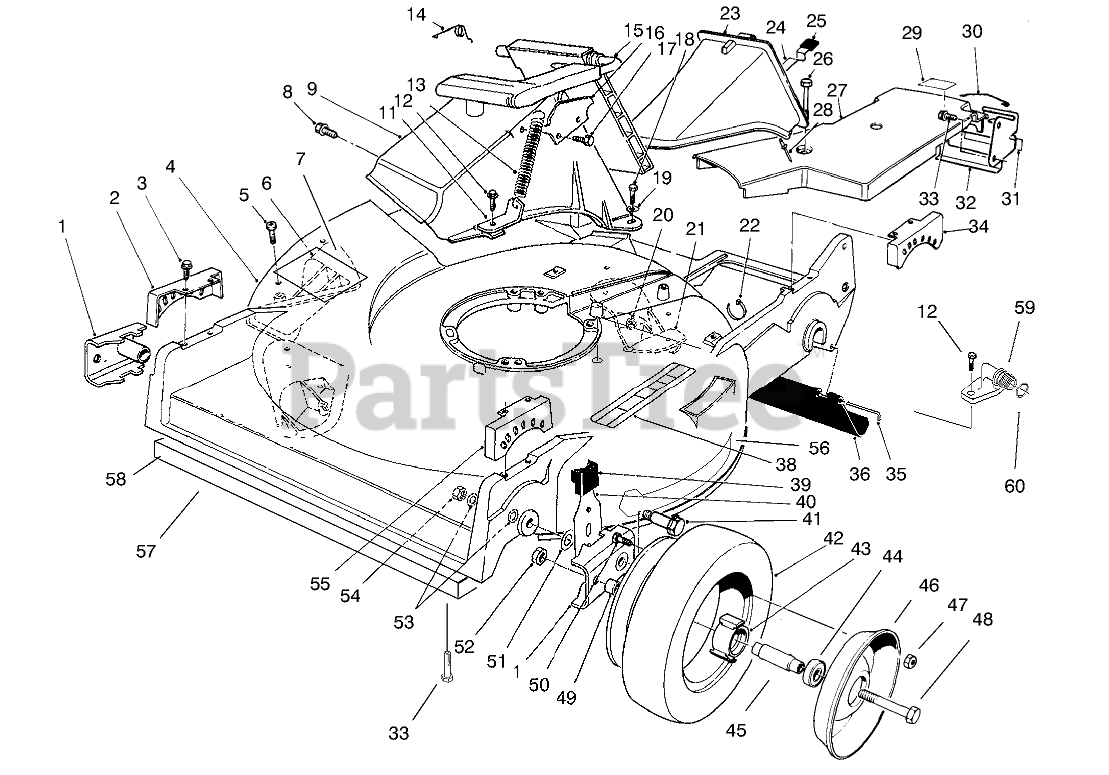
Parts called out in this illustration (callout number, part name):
1	ARM-PIVOT, FRONT
2	QUADRANT-FRONT, RH
3	SCREW-HWHTF
4	Housing-Commercial (Incl. Ref. #7)
5	SCREW-PPH
6	KICKER
7	DECAL-DANGER
8	SCREW AND WASHER ASM
9	DISCHARGE TUNNEL
11	Bracket-Spring
12	SCREW-HWH
13	SPRING-DOOR
14	RETAINER-DOOR
15	DOOR ASSEMBLY
16	DOOR LATCH PLATE
17	SCREW-PLASTITE
18	SCREW-HH
19	WASHER-FLAT
20	NUT-LOCK, NI
21	Plug-Discharge (Incl. Ref. #22, 23, & 28)
22	LATCH-PLUG, DISCHARGE
23	GRIP-LATCH
24	KICKER
25	PIN-COTTER
26	TIE-CABLE
27	SCREW-HHFTF
28	RIVET-HEAD, FLAT
29	BELT COVER
30	LABEL-GREASE
31	BRACKET-ADJUSTMENT, TRACTION
32	SCREW-HWHTF
33	QUADRANT-REAR, LH
34	SCREW-HWHTF
35	RETAINER-SPRING
36	SPRING
37	PIN-CABLE
38	Bracket-Spring
39	STEP PAD DECAL
40	PIN-SPRING
41	GUIDE-SPRING
42	ROD-SHIELD
43	SHIELD-TRAILING
44	KICKER
45	KNOB-ARM
46	FRONT SPRING ARM ASM
47	WHEEL BOLT
49	HUB-BEARING
50	SPACER-BEARING
51	BEARING-WHEEL
52	Wheel-Half
53	SCREW-HH
54	SPACER-WHEEL
55	SCREW-HH
56	WASHER-THRUST
57	NUT-LOCK, CONE
58	WASHER
59	Nut
60	QUADRANT-FRONT, LH
61	DECAL - RECYCLER
62	KICKER
63	SCREW-HH
64	RETAINER-CABLE
65	DECAL-POSITION, GEAR
